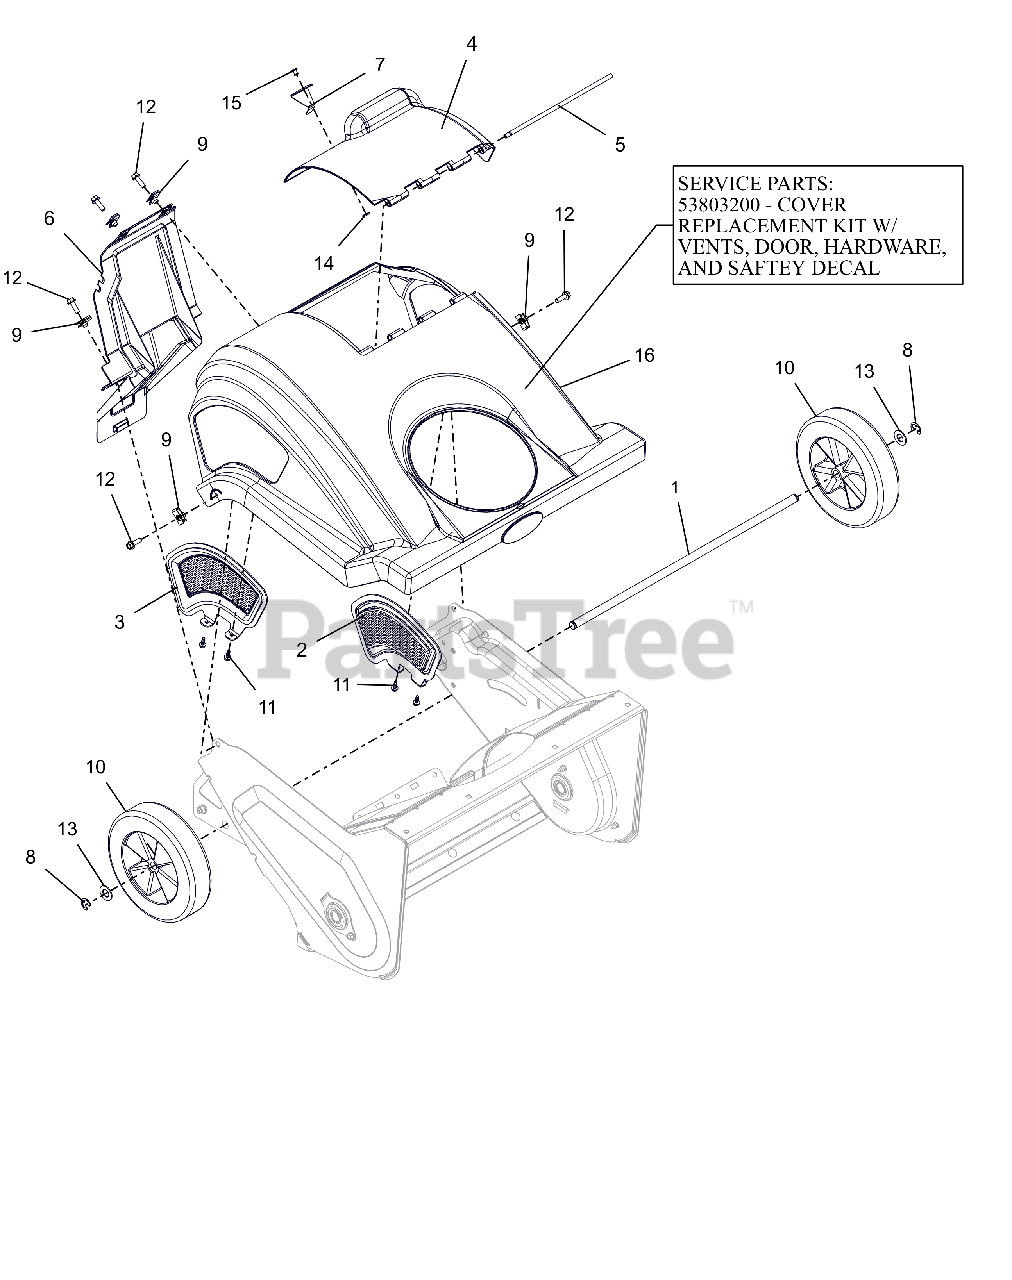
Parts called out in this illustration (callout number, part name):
1	SHAFT, AXLE
2	VENT, COVER LEFT
3	RIGHT VENT, COVER
4	DOOR, COWEL COVER
5	ROD, COVER, SINGLE STAGE
6	BACK COVER, NON ELEC. START
7	TAB, LATCH
8	RG-RTNG-EXT .500X.042 (E)
9	NUT-RTNR .25-20X.56
10	WHL 7.50" .50 BORE, 1.50 HUB
11	SCR-TAP #10X.50 BOSS INDHXHD
12	BLT-HEX .25-20X.75 HWH YZ GR5
13	WSHR-FL-STL.531X1.00X.063 YWZC
14	WSHR-FL-STL .196X.500X.06 YZ
15	RVT-POP .187 YZ
16	KIT, COWL REPLACEMENT
